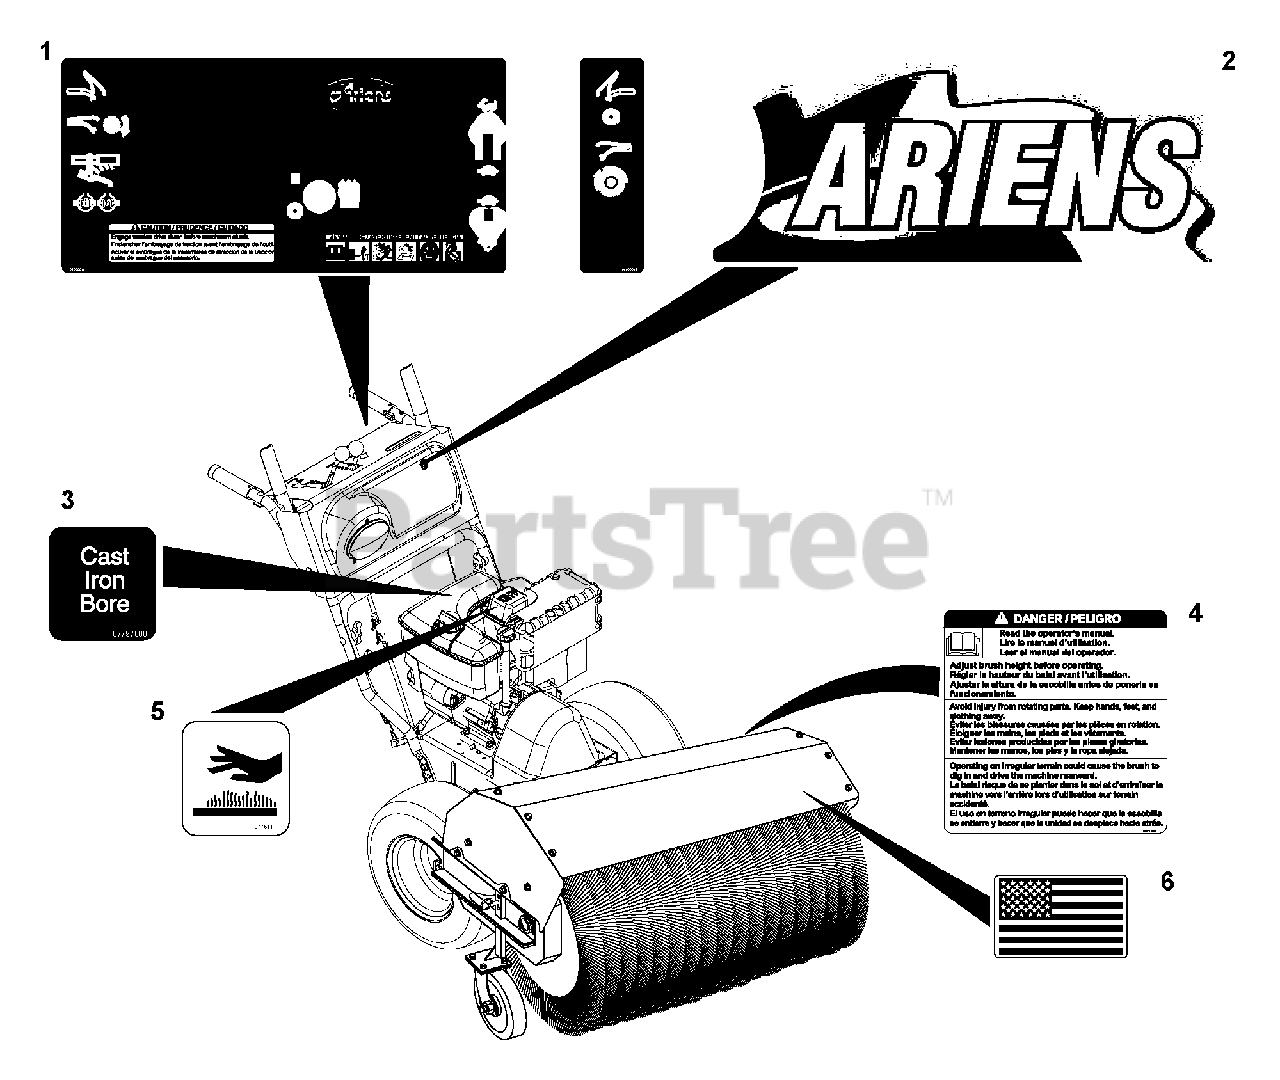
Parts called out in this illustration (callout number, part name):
1	DECAL, CONTROL-ARIENS PB
2	DECAL, FRONT DASH-ARIENS BRUSH
3	DECAL - CAST IRON BORE
4	DECAL, DANGER - POWER BRUSH
5	DECAL, HOT SURFACE
6	DECAL, AMERICAN FLAG
